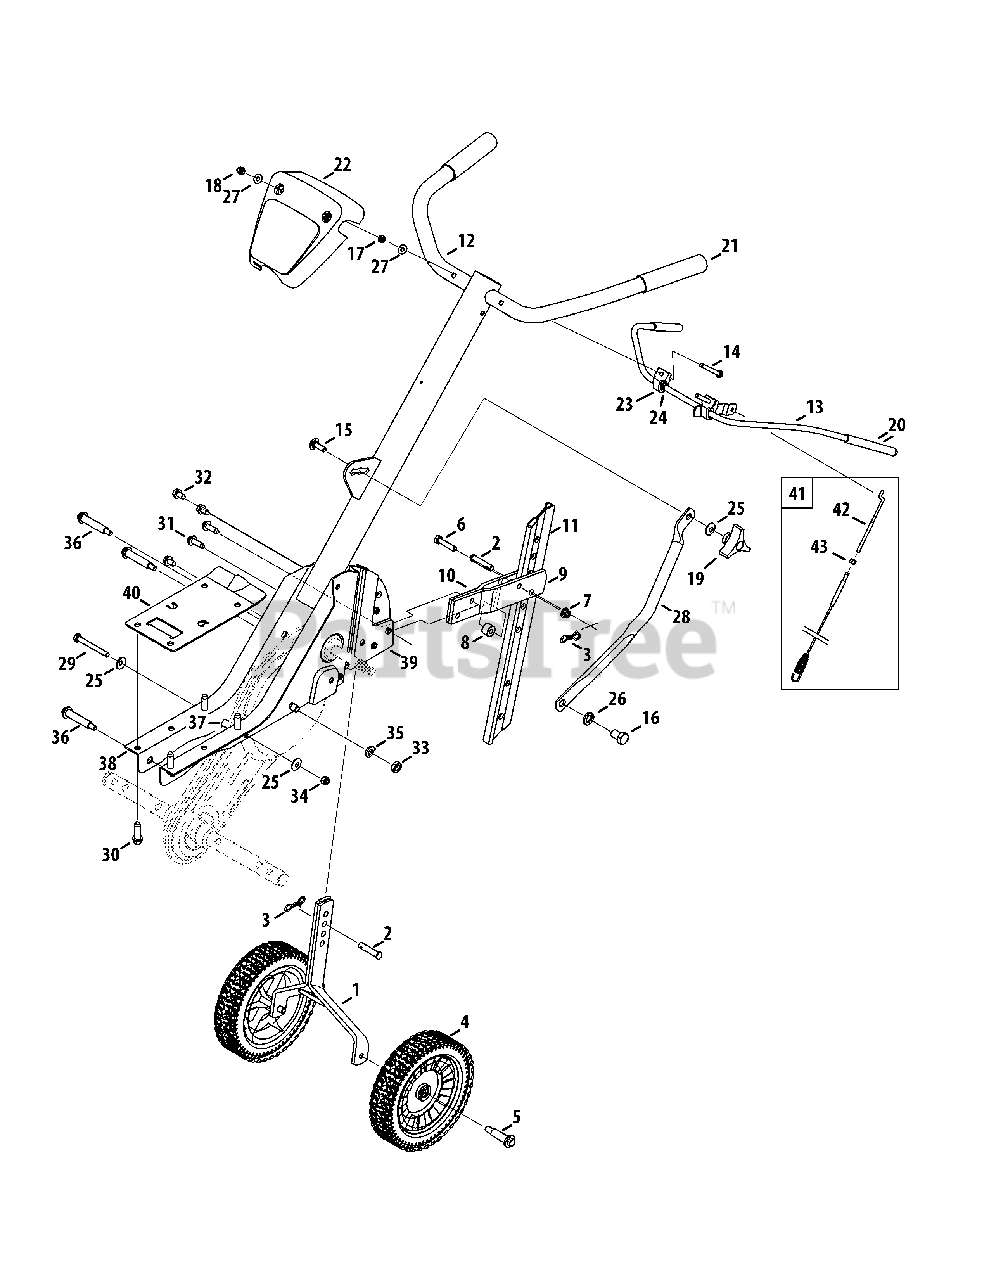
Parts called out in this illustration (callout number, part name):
1	Wheel Bracket Assembly
2	Clevis Pin, .375 x 1.75
3	Bow Tie Cotter Pin
4	Complete Wheel Assy. 8 x 1.75
5	Shoulder Screw, .496 x 1.445 3/8-16
6	Hex Head Screw, 5/16-18 x 1.50
7	Nut, 5/16-18, Flange Lock
8	Spacer, .325 ID x .75 OD x .520
9	Tail Bracket, LH
10	Tail Bracket, RH
11	Depth Bar
12	Complete Handle Assembly
13	Clutch Bail
14	Hex Head Screw, 1/4-20 x 2.25
15	Carriage Screw, 5/16-18 x 1.00
16	Hex Head Screw, 1/2-20 x .750
17	Jam Nut, 1/4-20
18	Nut, 1/4-20, Lock
19	Handle Knob
20	Grip, Clutch Bail
21	Grip, Handle
22	Handle Cover
23	Clutch Bail Holder
24	Flat Washer, .385 x .62 x .063
25	Bell Washer, .340 x .872 x .060
26	Lock Washer, 1/2
27	Flat Washer, .271 x .630 x .065
28	Handle Brace
29	Hex Head Screw, 5/16-18 x 2.75
30	SEMS Screw, 3/8-16
31	Self-Tapping Screw, 5/16-18 x 1.00
32	Self-Tapping Screw, 5/16-18 x .625
33	Jam Nut, 7/16-20
34	Nylon Hex Lock Nut, 5/16-18
35	Lock Washer, 7/16
36	Shoulder Screw, .475 x 2.11 5/16-18
37	Spacer, .47 OD x .96
38	Frame, RH
39	Frame, LH
40	Engine Mounting Plate
41	Forward Clutch Cable
42	Z-Fitting (incl. Ref 43)
43	Jam Nut
